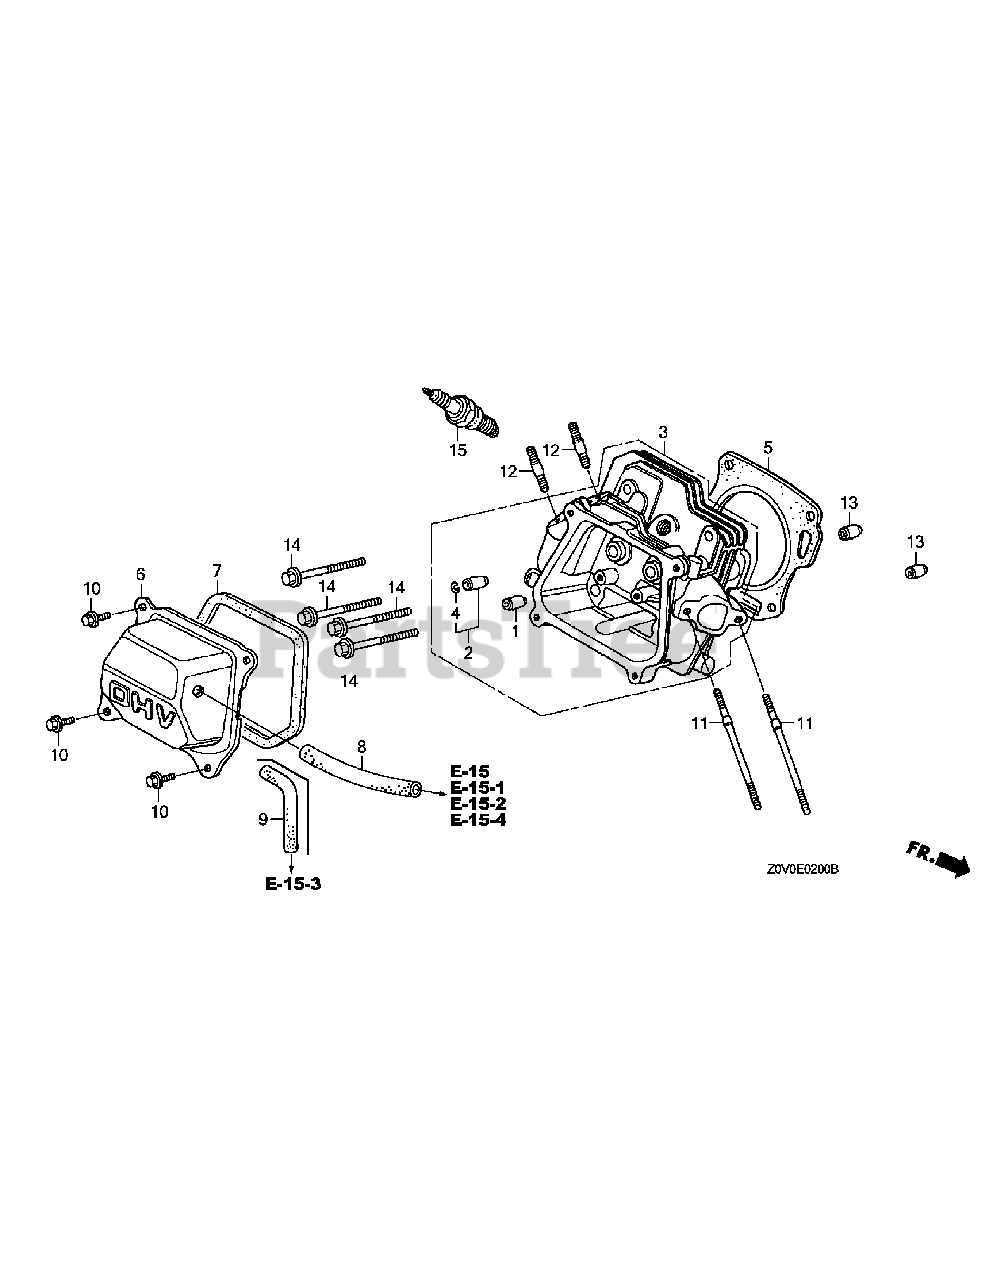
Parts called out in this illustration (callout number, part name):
1	Guide, In. Valve(O.S.)
2	Guide, Ex. Valve(O.S.)
3	Head Comp., Cylinder
4	Clip, Valve Guide
5	Gasket, Cylinder Head
6	Cover Comp., Head
7	Packing, Head Cover
8	Tube, Breather
9	Tube, Breather
10	Bolt, Flange, 6X12(Ct200)
11	Bolt, Stud, 6X112
12	Bolt, Stud, 8X32
13	Dowel Pin, 10X16
14	Bolt, Flange, 8X60
15	Plug, Spark(Bpr6Es)(Ngk)
15	Plug, Spark(Bpr5Es)(Ngk)
